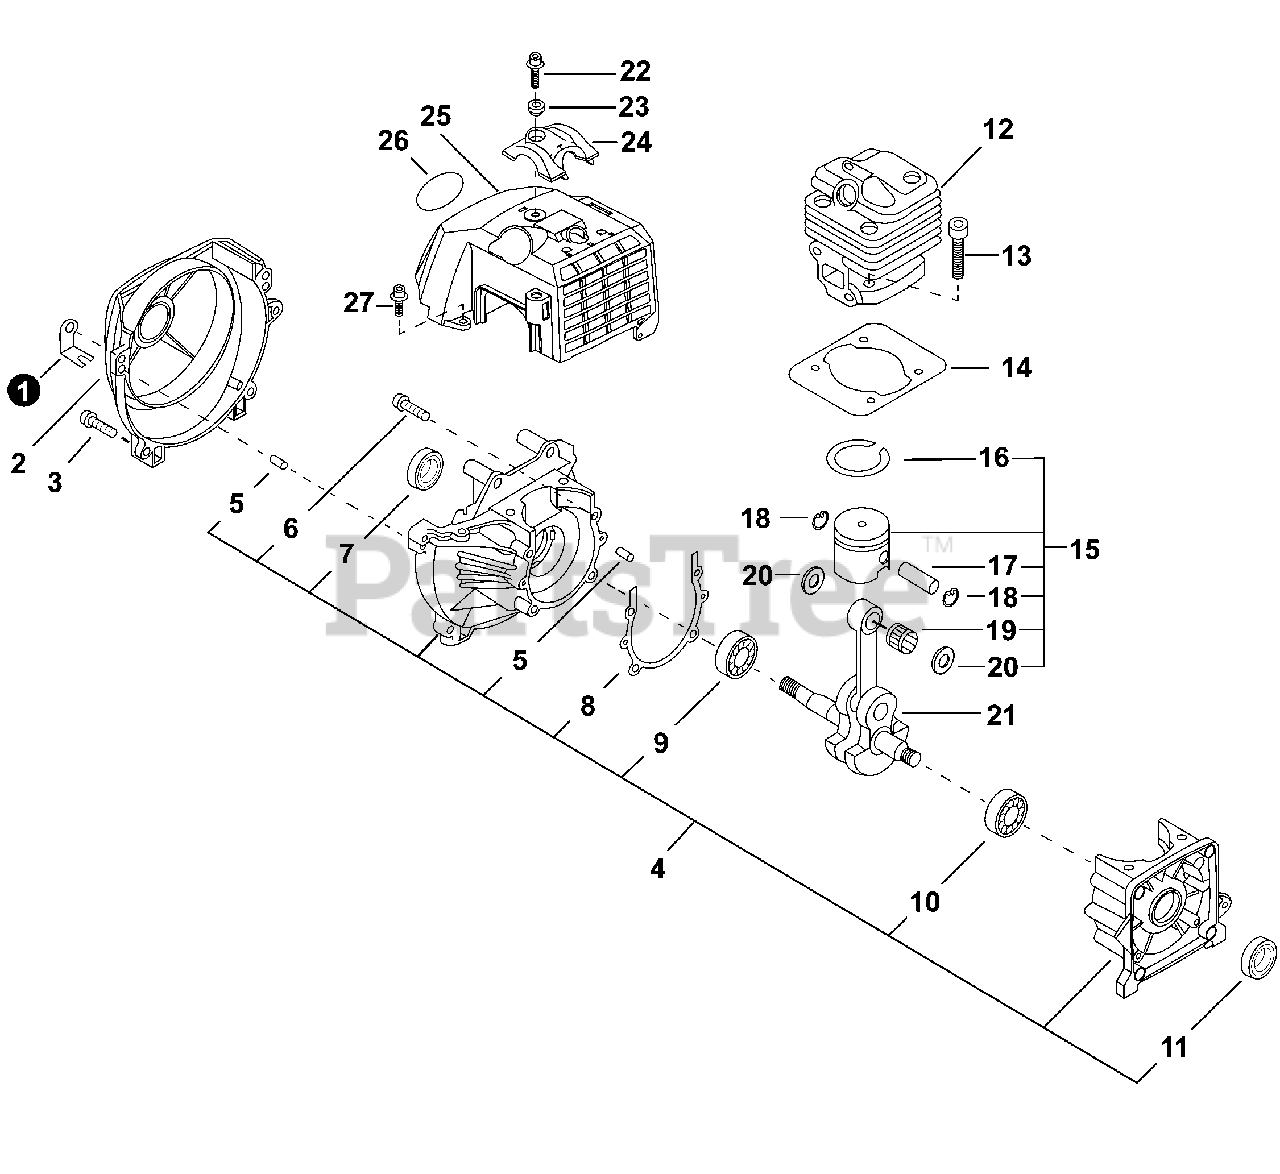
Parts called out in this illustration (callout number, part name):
1	HOLDER, CABLE
2	COVER, FAN
3	BOLT 5×20
4	CRANKCASE KIT
5	PIN, LOCATING 4×8
6	BOLT M5×35
7	SEAL, OIL
8	GASKET, CRANKCASE
9	BEARING, BALL 6201
10	BEARING, BALL 6202
11	SEAL, OIL 12
12	CYLINDER
13	BOLT 5×20
14	GASKET, CYLINDER
15	PISTON KIT
16	RING, PISTON
17	PIN, PISTON 10
18	RING, SNAP Ø10
19	BEARING, NEEDLE 10
21	CRANKSHAFT ASSY
22	BOLT 5×20
23	COLLAR 5
24	GUARD, TOP
25	COVER, ENGINE
26	LABEL - MODEL B430
27	BOLT 5×12
